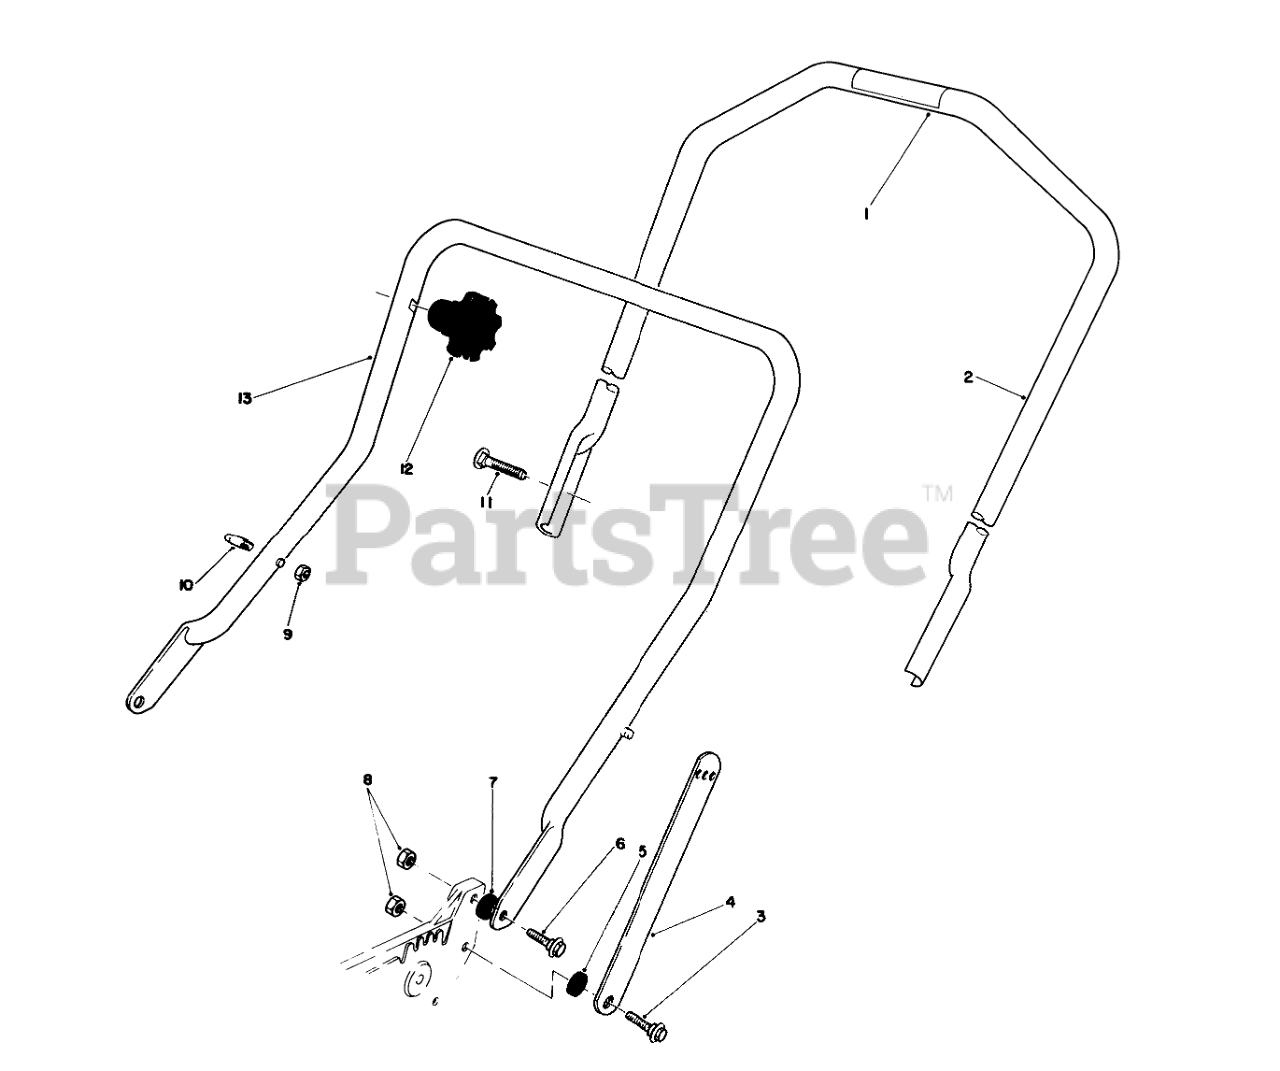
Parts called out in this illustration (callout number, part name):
1	DANGER DECAL
2	Handle-Upper (Incl. Ref. #1)
3	SCREW-SHOULDER
4	Handle Latch
5	SPACER
6	SCREW-SHOULDER
7	SPACER
8	NUT-LOCK, NI
9	NUT-LOCK, NI
10	HANDLE PIN
11	5/16-18 X 2 HNDLE SCREW
13	LOWER HANDLE ASM
